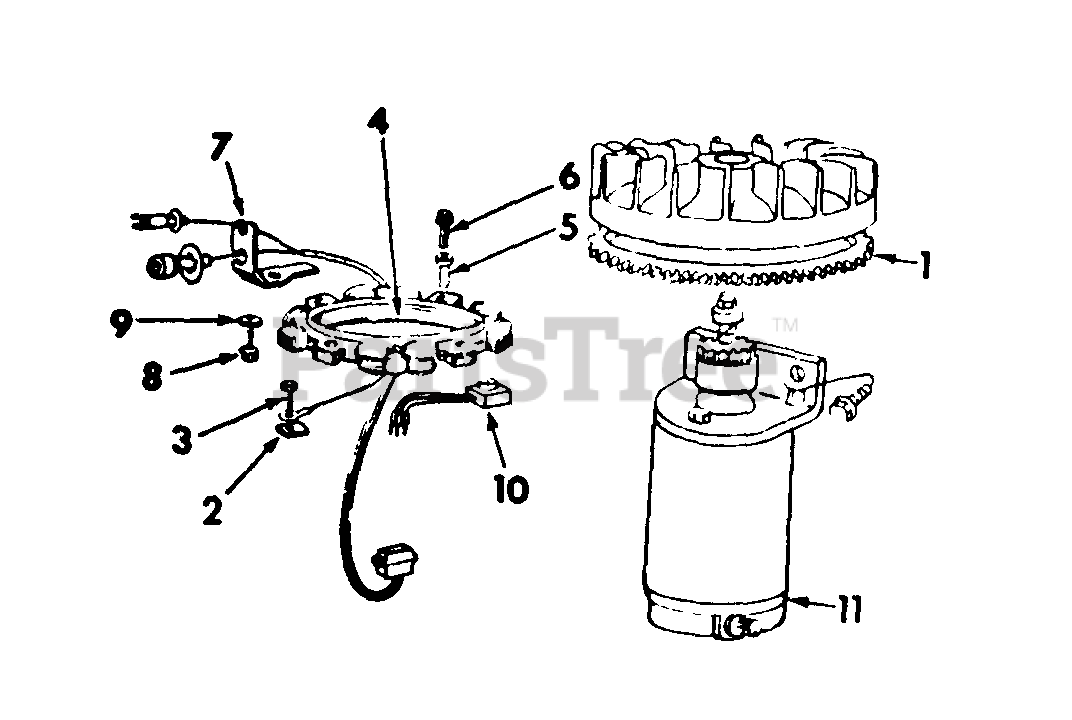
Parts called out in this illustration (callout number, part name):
1	GEAR, FLYWHEEL RING
3	SCREW, 8-32 X 3/8 HEX-HD
4	STATOR W/BRACKET, ALTERNATOR
5	BUSHING, STATOR
6	SCREW, STATOR MTG
7	BRACKET, FUSE
8	SCREW, BRACKET MTG
9	WASHER, BRACKET
11	MOTOR ASSY, STARTER
